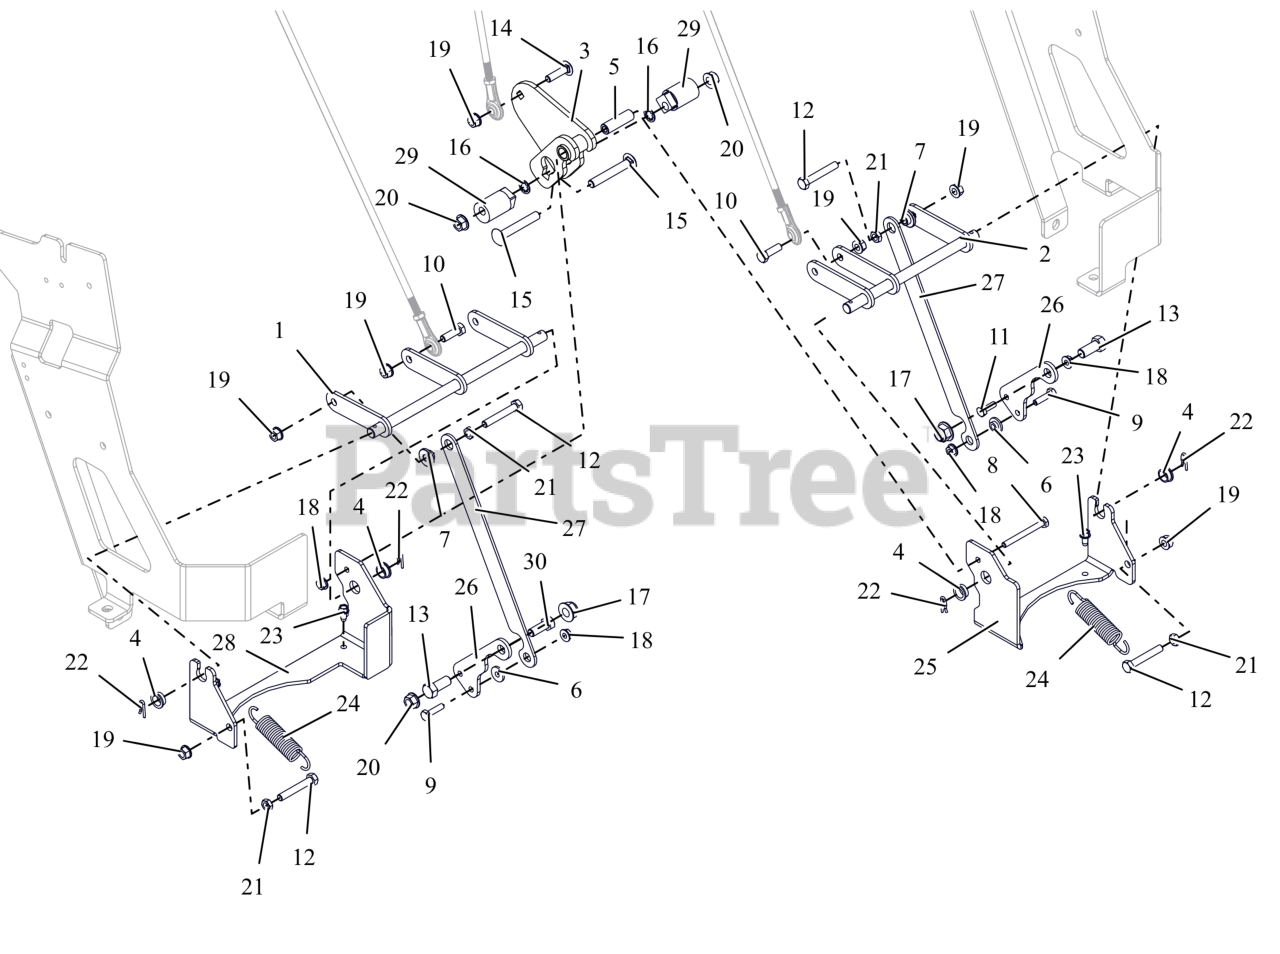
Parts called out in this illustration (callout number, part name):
1	WLDMT, RH LOWER STEERING SHAFT - 36" (BLACK)
2	WLDMT, LH LOWER STEERING SHAFT 36" (BLACK)
3	WLDMT, SPEED STOP
4	BSHG,FLANGE .500X.625X.270X.75
5	BSHG, SLV .265X.505X1.665
6	BSHG-FLG .265X.437X.250X.750
7	BSHG-FLG .32X.500X.344X.880
8	BLT, HEX 0.25-20X2.5 GR8 ZCC
9	BLT,HEX .25-20X1.00 G5 ZCC
10	BLT,HEX .31-18X1.00 G5 ZCC
11	BLT, HEX .25-20X.75 G5 ZCC
12	BLT, HEX .31-18X2.00 G5 ZCC
13	BLT, HEX 0.4375-14X1 GR5 ZCC
14	BTL,RHSSN .313-18 X 1.25 G5 ZCC
15	BLT, RHSSN.38-16X2.50 G5 ZCC
16	WSHR-LK .38 INT STAR YWZC
17	NUT,NYL-FLG .44-14 GF ZCC
18	NUT-LK-CTR-FLG .25-20 ZC120
19	NUT,LK-CTR-FLG .31-18 GF ZCC
20	NUT-LK-CTR-FLG .375-16 GF ZCC
21	NUT-JAM .312-18 G2 ZCC
22	CLIP, SPRING
23	SCR-TAP .25-20X.50 HWH ZCC
24	SG-TENS .105X.812X3.88 WLD 15
25	BRKT, LH LOWER STEERING 36" (BLACK)
26	PLATE, TRANSAXLE ADAPTER (BLACK)
27	LINK, STEERING (BLACK)
28	BRKT, RH LOWER STEERING 36" (BLACK)
29	ECCENTRIC - .390X1.000X1.750
30	BLT,HEX .38-16X1.00 G5 ZCC
